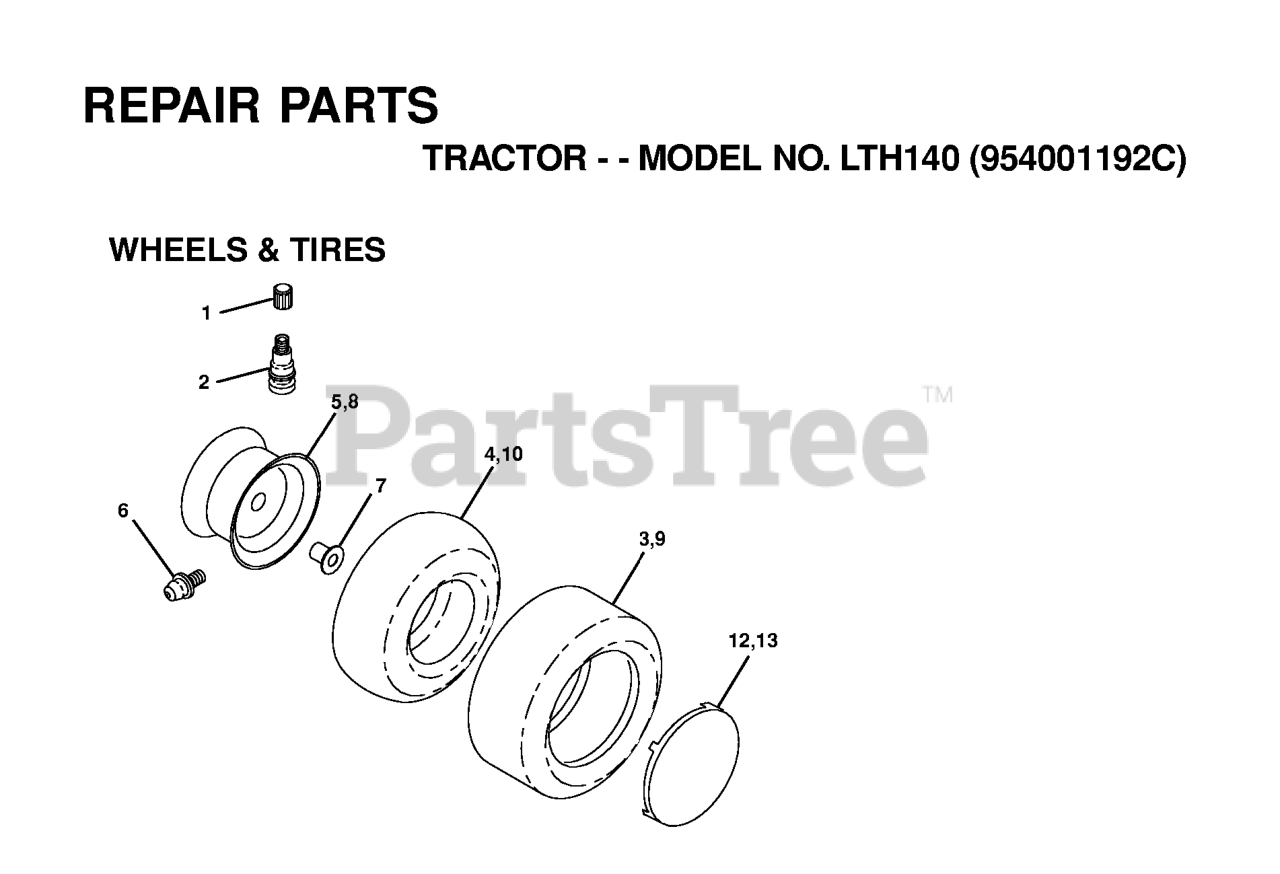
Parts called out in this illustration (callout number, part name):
2	VALVE STEM LT
3	TIRE HEAVY DUTY
4	TUBE.5.3/4.5/6
5	RIM FRONT 6"
6	FITTING LT
7	BEARING T
8	RIM.ASM.8X7.REAR.WHITE
9	TIRE.TS.20X10-8
10	TUBE
12	COVER.FRONT.WHEEL
13	CAP,HUB REAR
